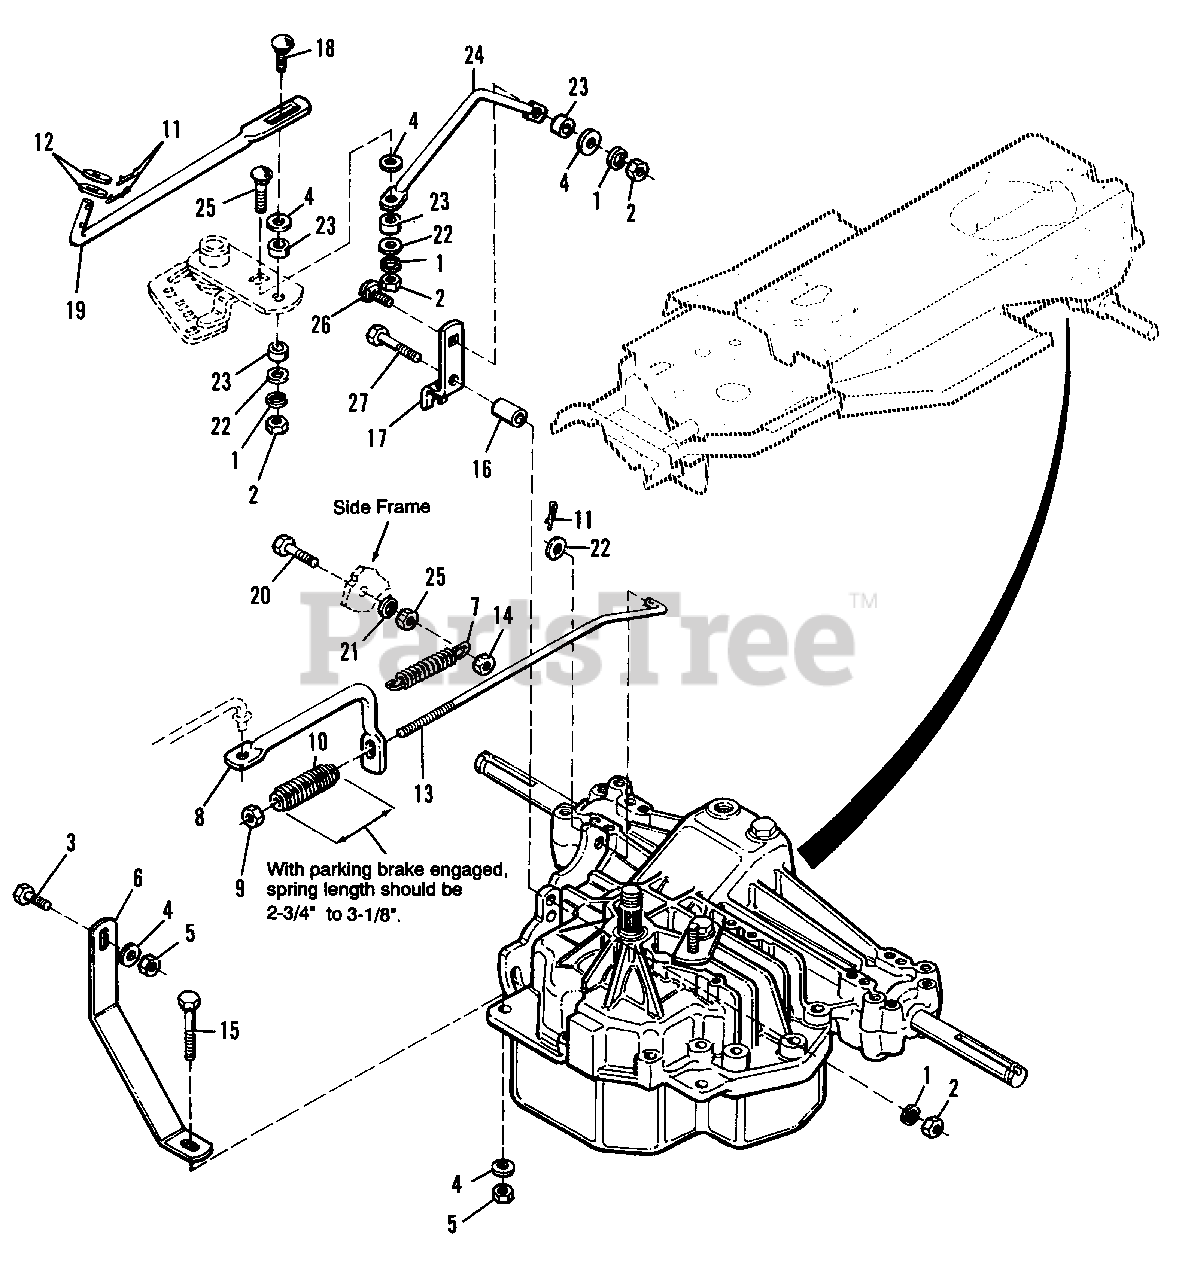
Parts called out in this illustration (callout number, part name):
1	LOCKWASHER, 5/16
2	NUT, Hex, Full, 5/16-18
3	SCREW, Hex, Whizlock, 5/16-18 x 3/4
4	WASHER, 11/32 x 1 x 1/8
5	NUT, Hex, Flange Lock, 5/16-18
6	TORQUE STRAP
7	SPRING, Brake Arm
9	NUT, Hex, Nylon Lock, 5/16-18
11	COTTER PIN
12	WASHER, 17/32 x 1-1/4 x 5/64
14	JAMNUT, Hex, Lock, 3/8-16
15	SCREW, Hex, Whizlock, 5/16-18 x 2-1/4
17	LEVER, Control
18	CARRIAGE BOLT, 5/16-18 x 1-1/4
19	ROD, Shift, Front
20	CAPSCREW, hex, 3/8-16 x 1-1/4
21	LOCKWASHER, 3/8
22	WASHER, Plain, 5/16
24	ROD, Shift Rear
25	NUT, Hex, Full, 3/8-16
26	CARRIAGE BOLT, 5/16-18 x 1
27	CAPSCREW, Hex, 5/16-18 x 1-3/4
